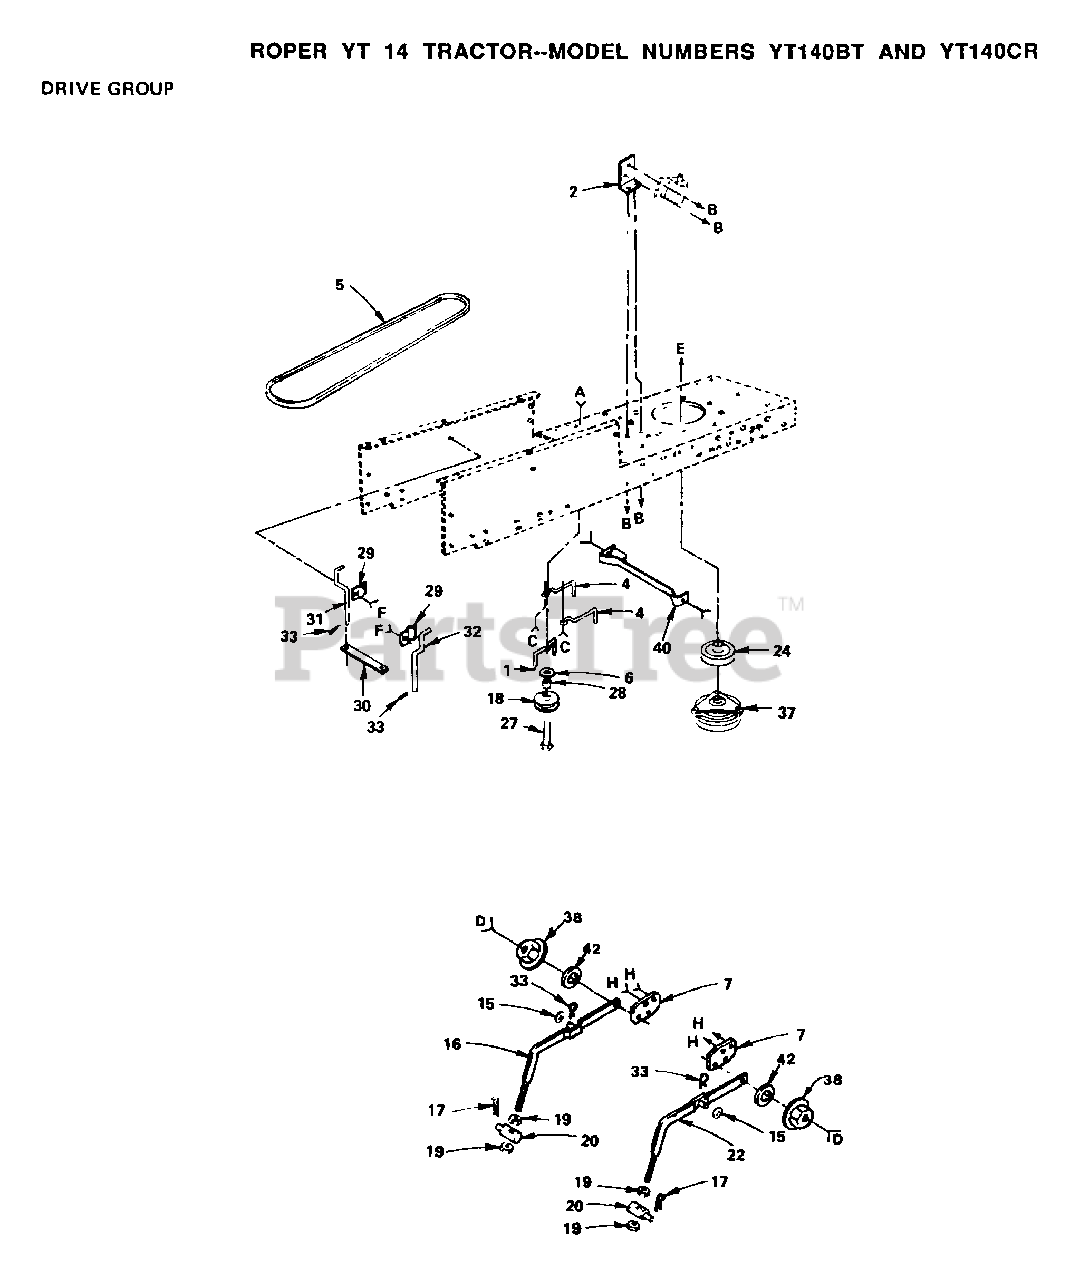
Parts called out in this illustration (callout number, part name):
1	BELT KEEPER LT
2	BRACKET LT
4	"KEEPER,BLT ENG LT"
6	WASHER
7	"BRACKET, SUSPE T"
17	SPRING H
19	NUT
27	BOLT
28	SPACER T
29	CLAMP LT
32	KEEPER BELT RH
33	SPRING.RETAINER
38	NUT SPECIAL T
42	WASHER T
